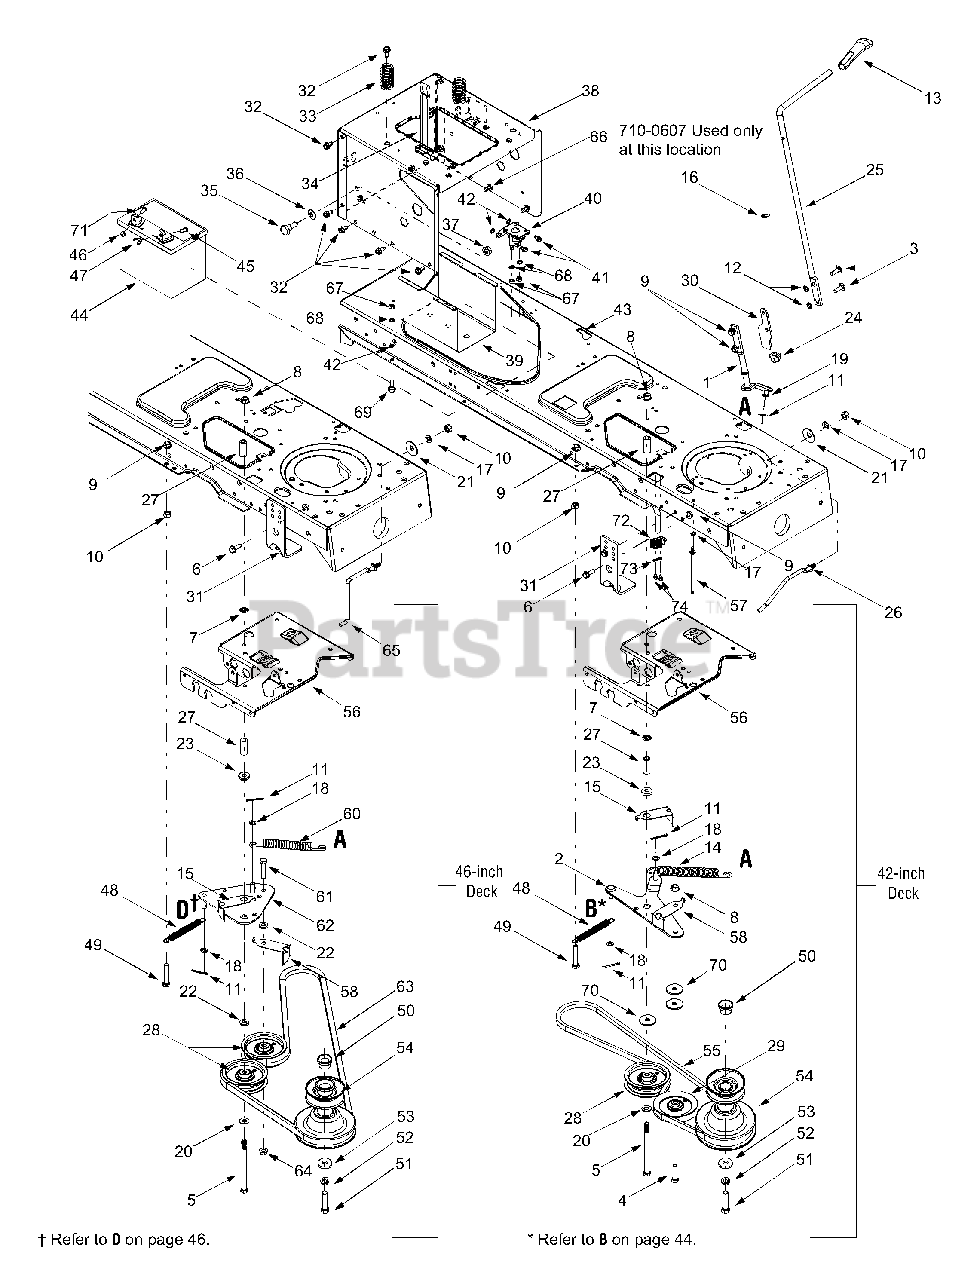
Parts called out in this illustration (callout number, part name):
1	PTO Engage Lever Assembly
4	Hex Cap Screw, 3/8-16 x 1.5
5	Hex Cap Screw, 3/8-16 x 5.5
6	Hex Head Washer Screw, 5/16-18 x.875
7	Push Nut, 3/8
8	Flange Lock Nut, 3/8-16
9	Flange Lock Nut, 5/16-18
10	Hex Nut, 5/16-18
11	Cotter Pin, 1/8 x 1.25
12	Speed Nut,.3125
13	PTO Knob
14	Extension Spring,.75 x 6.75
15	Belt Guard
16	Flat Washer,.510 x.750 x.033
17	Lock Washer, 5/16
18	Flat Washer, .385 x .62 x .063
19	Flat Washer, 5/16
20	Flat Washer,.406 x.875 x.059
21	Bell Washer,.345 x.88 x.060
22	Flat Washer,.407 x.812 x.135
23	Shoulder Spacer,.380
24	Hex Split Flange Bearing,.5
26	Belt Keeper Rod
27	Spacer, 3/8 x 1.54
28	Idler Pulley, 3.5
29	Idler Pulley, 4.0
32	Self Tapping Screw, 5/16-18 x.625
33	Compression Spring, 1.28 x 3.5
34	Battery Strap
35	Shoulder Screw,.625 x.5, 7/16-20
36	Bell Washer,.45 x 1.0 x.062
37	Flange Lock Nut, 7/16-20
41	Self Tapping Screw, 1/4-20 x.5
42	Lock Washer, 1/4
45	Hex Cap Screw, 1/4-20
46	Hex Sems Nut, 1/4-20
47	Wing Nut, 1/4-20
48	Extension Spring,.50 x 5.0
49	Hex Cap Screw, 5/16-18 x 1.75
50	Spacer Cup
51	Hex Head Cap Screw, 7/16-20 x 1.25
52	Lock Washer, 7/16
53	Flat Washer,.450 x 1.25
54	Engine Pulley, 3.56 OD x 5.56
54	Engine Pulley, 3.56 OD x 6.12
55	PTO Belt (Models w/ 42-inch deck)
57	Keeper Pin, 5/16 x 4.75
58	Belt Guard
59	Hex Cap Screw, 5/16-18 x.625
60	Extension Spring,.75 x 6.75
61	Hex Cap Screw, 3/8-16 x 1.75
63	PTO Belt (Models w/ 46-inch deck)
64	Flange Lock Nut, 3/8-16
65	Belt Keeper Rod
66	Self-tapping Screw, 5/16-18 x.5
67	Hex Nut, 1/4-20
68	Lock Washer, 1/4
69	Self-tapping Screw, 1/4-20 x.75
70	Flat Washer,.406 x 1.5 x 11 gauge
71	Carriage Bolt, 1/4-20 x.75
72	Safety Interlock Switch
73	Switch Plate
74	Screw, #10 x.5
